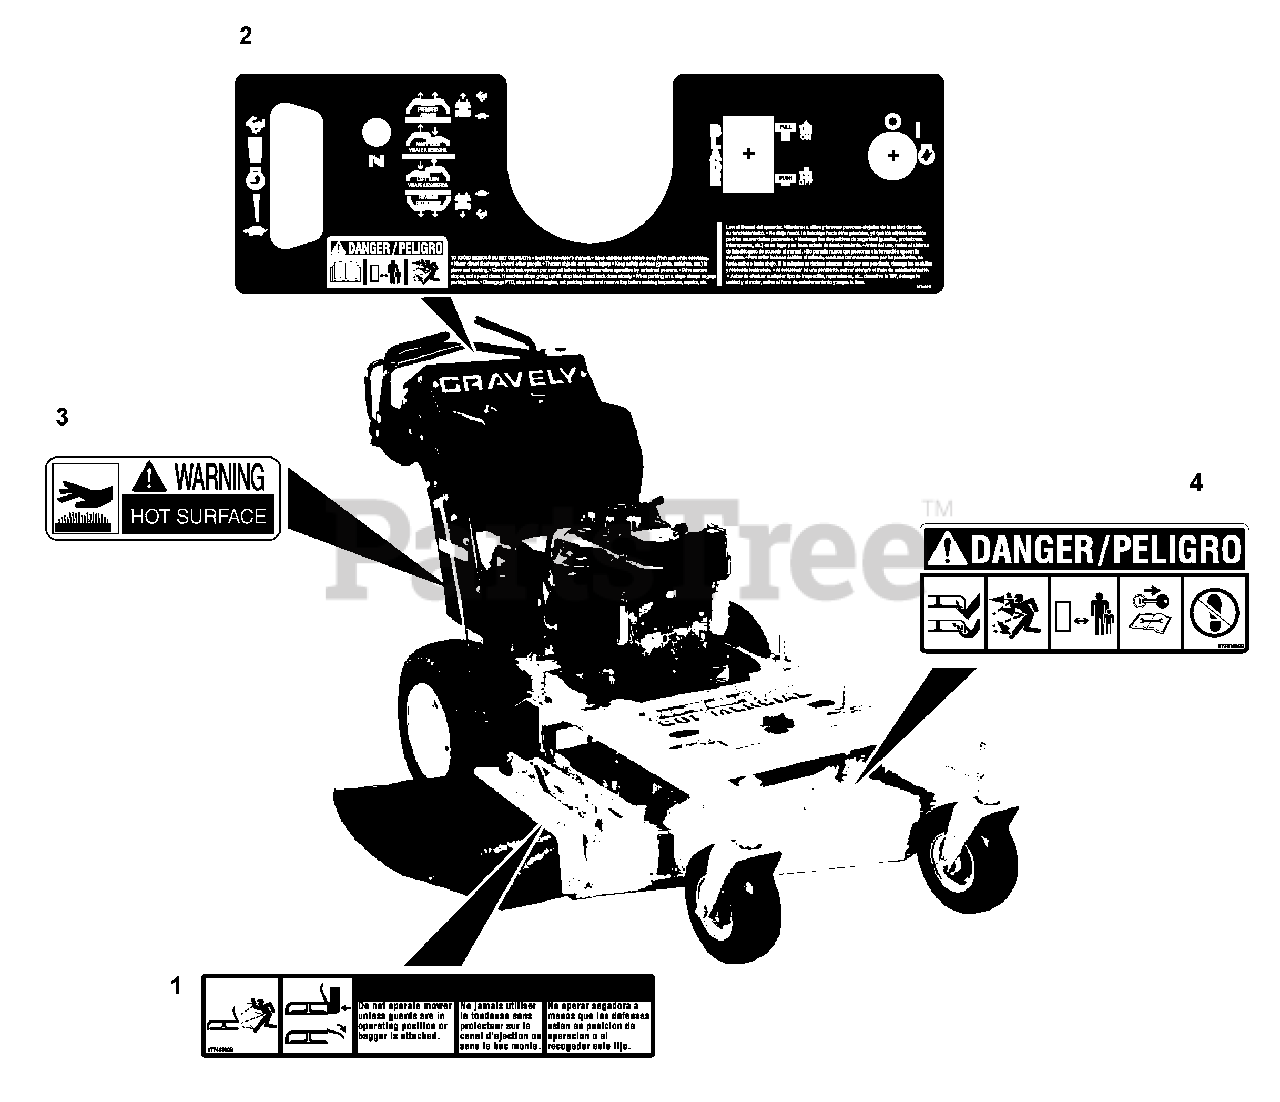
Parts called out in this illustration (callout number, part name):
1	Decal, Warning
2	Decal, Console
3	Decal, Warning Hot Surface
4	Decal, Mower Pan Danger
